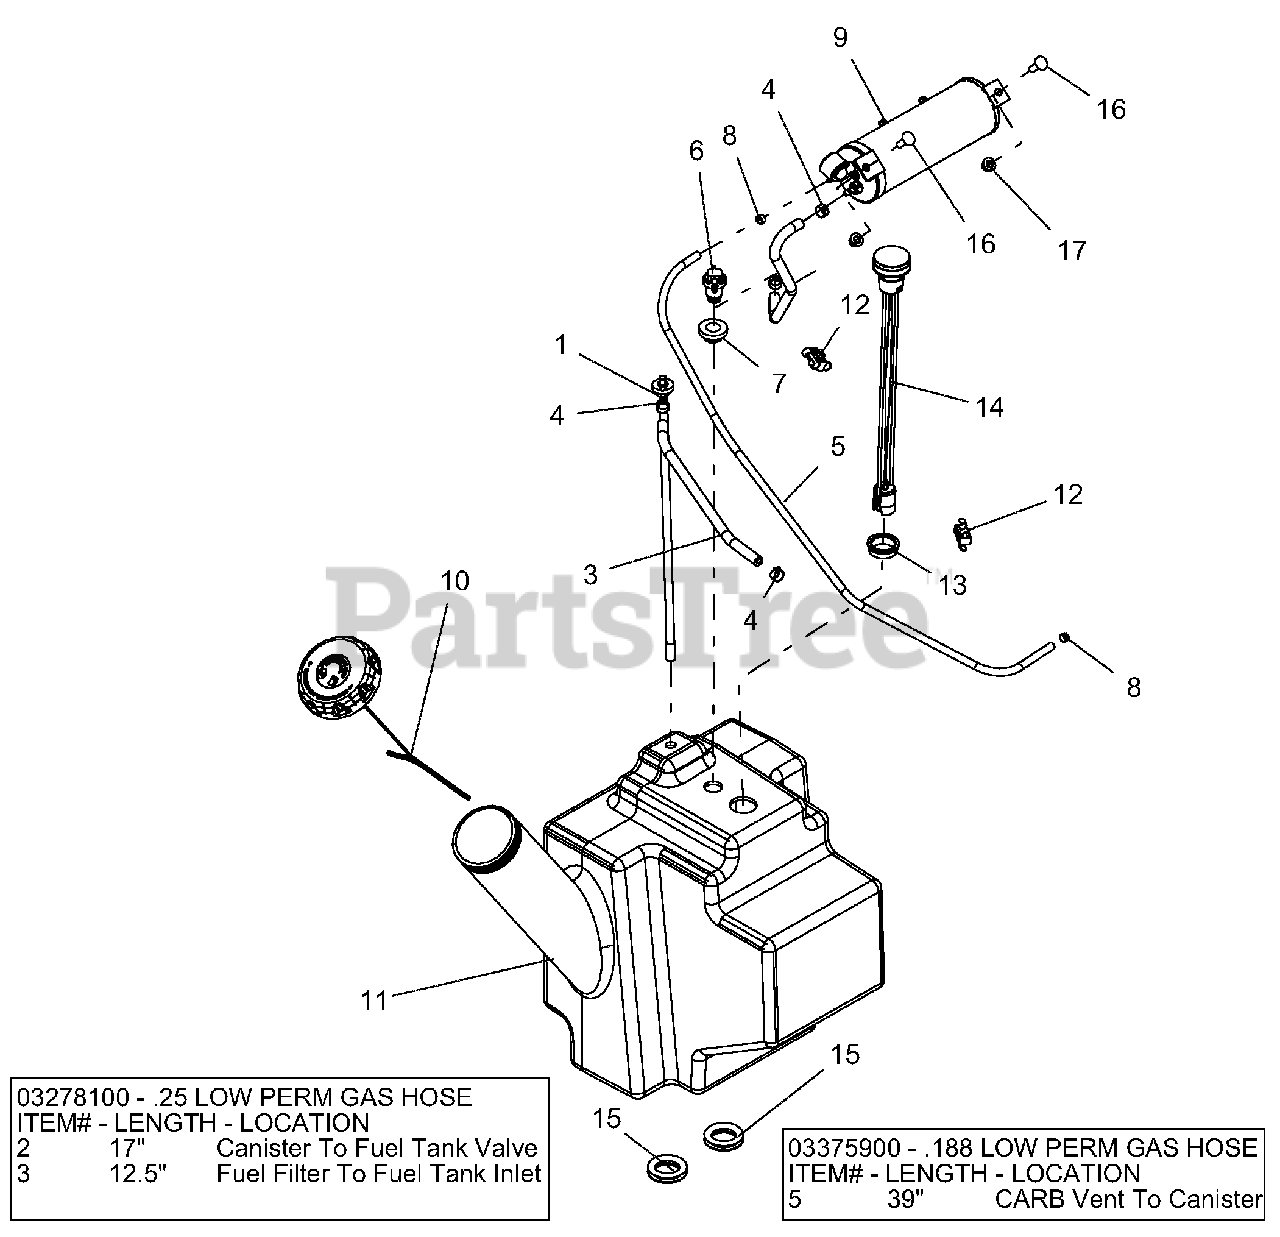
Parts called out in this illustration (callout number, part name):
1	ASM, LARGE TANK FUEL PICK-UP
2	.25 LOW PERM GAS HOSE
3	.25 LOW PERM GAS HOSE
4	CLAMP, FUEL LINE
5	HOSE, .188 LOW-PERM BULK GAS
6	VALVE, COMBINATION
7	GROMMET, REMOTE VENT NITRILE
8	CLAMP - HOSE, SPRING .188
9	CANISTER, CARBON 9.3 GAL
10	CAP, FUEL NON-VENT AUTOLOCK
11	TANK, FUEL COMPACT PROSTANCE
12	CLIP, T, .38-.50
13	GROMMET, FUEL GAUGE
14	GAGE, REMOTE FUEL SEALED 15"
15	GROMMET, 1.25"
16	BLT-RDHDSQSHNK .31-18X1.00 G5 Y
17	NUT-LK-NYL-FLG .31-18 YWZC
